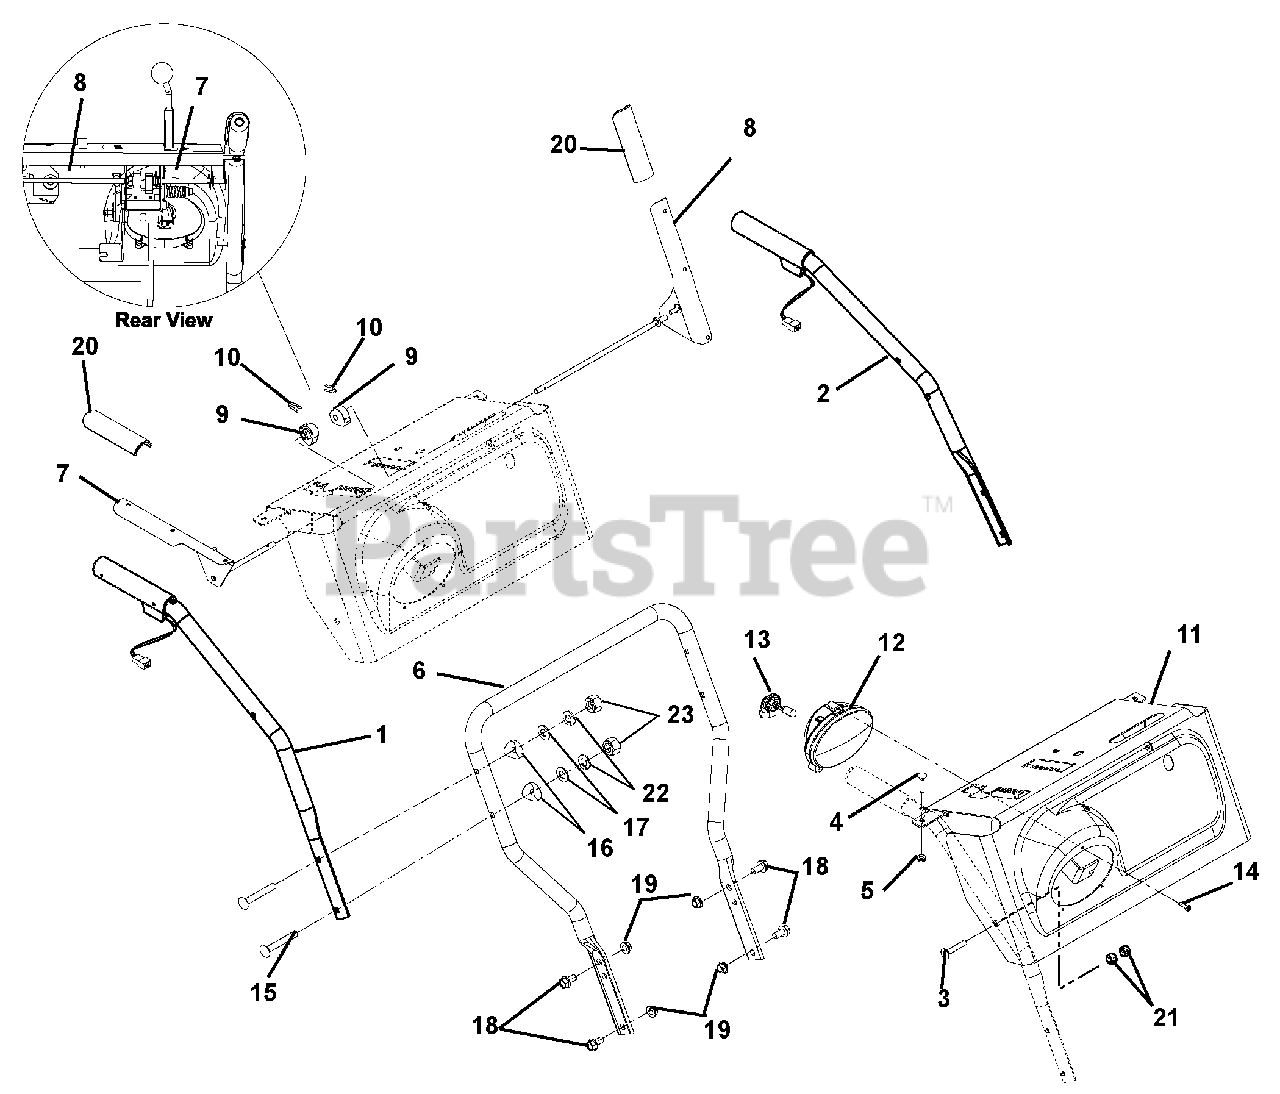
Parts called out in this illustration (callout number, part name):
1	Handlebar, Upper Right Hand with Handwarmer
2	Handlebar, Upper Left Hand with Handwarmer
3	Bolt, Round Head Square Neck .31-18 x 1.75 Grade 5
4	Bolt, Round Head Square Neck .25-20 x 1.25
5	Nut, Locking Center .25-20
6	Handlebar, Lower
7	Lever, Right Hand-Attachment
8	Lever, Left Hand-Traction
9	Cam, Interlock
10	Pin, Spring Clip
11	Panel with Control Decal Gravely Brush
12	Light, Halogen Assy. (Bulb Included)
13	Bulb, Light Halogen
14	Screw, Tapping 10-16 x .75 Hi-Lo
15	Bolt, Round Head Square Neck .31-18 x 2.25
16	Spacer, Handlebar
17	Washer, Flat-Steel .38 x .875 x .083
18	Bolt, Screw Hex Flanged Whiz Lock Head .38-16 x .75
19	Nut, Locking-Top-Flange .38-16
20	Grip, Clutch Lever
21	Nut, Locking-Center .31-18
22	Washer, Locking .31 x .078 Regular
23	Nut, Locking-Nylon .312-18
